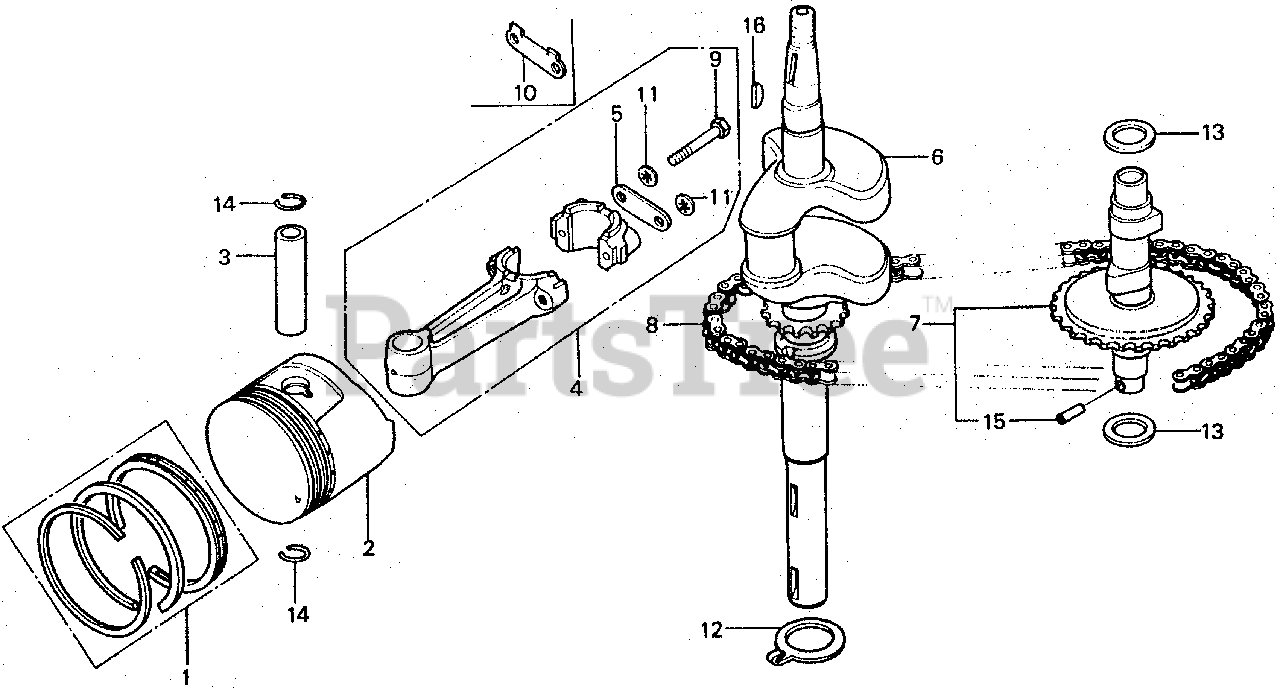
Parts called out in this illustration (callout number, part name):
1	RING SET, PISTON (STD)
1	RING SET, PISTON (OS 0.25)
1	RING SET, PISTON (OS 0.50)
1	RING SET, PISTON (0.75) (OS)
2	PISTON (STD)
2	PISTON (OS 0.25) (OS)
2	PISTON (OS 0.50) (OS)
2	PISTON (0.75) (OS)
3	PIN, PISTON
4	ROD ASSY., CONNECTING
5	WASHER A, CONNECTING ROD
5	WASHER, CONNECTING ROD
6	CRANKSHAFT, R.
7	CAMSHAFT ASSY.
8	CHAIN, CAM
8	CHAIN, CAM (NOT AVAILABLE)
9	BOLT, CONNECTING ROD (6MM)
9	BOLT, CONNECTING ROD (6MM) (NOT AVAILABLE)
9	BOLT, CONNECTING ROD (7MM)
10	WASHER B, CONNECTING ROD
11	WASHER, LOCK (6MM) (N/A: SEE ASSEMBLY)
11	WASHER, LOCK (7MM)
12	WASHER, THRUST (35MM)
13	WASHER, THRUST (18MM)
14	CLIP, PISTON PIN (15MM)
15	PIN, SPRING (2.5X16)
16	KEY, SPECIAL WOODRUFF (25X18)
